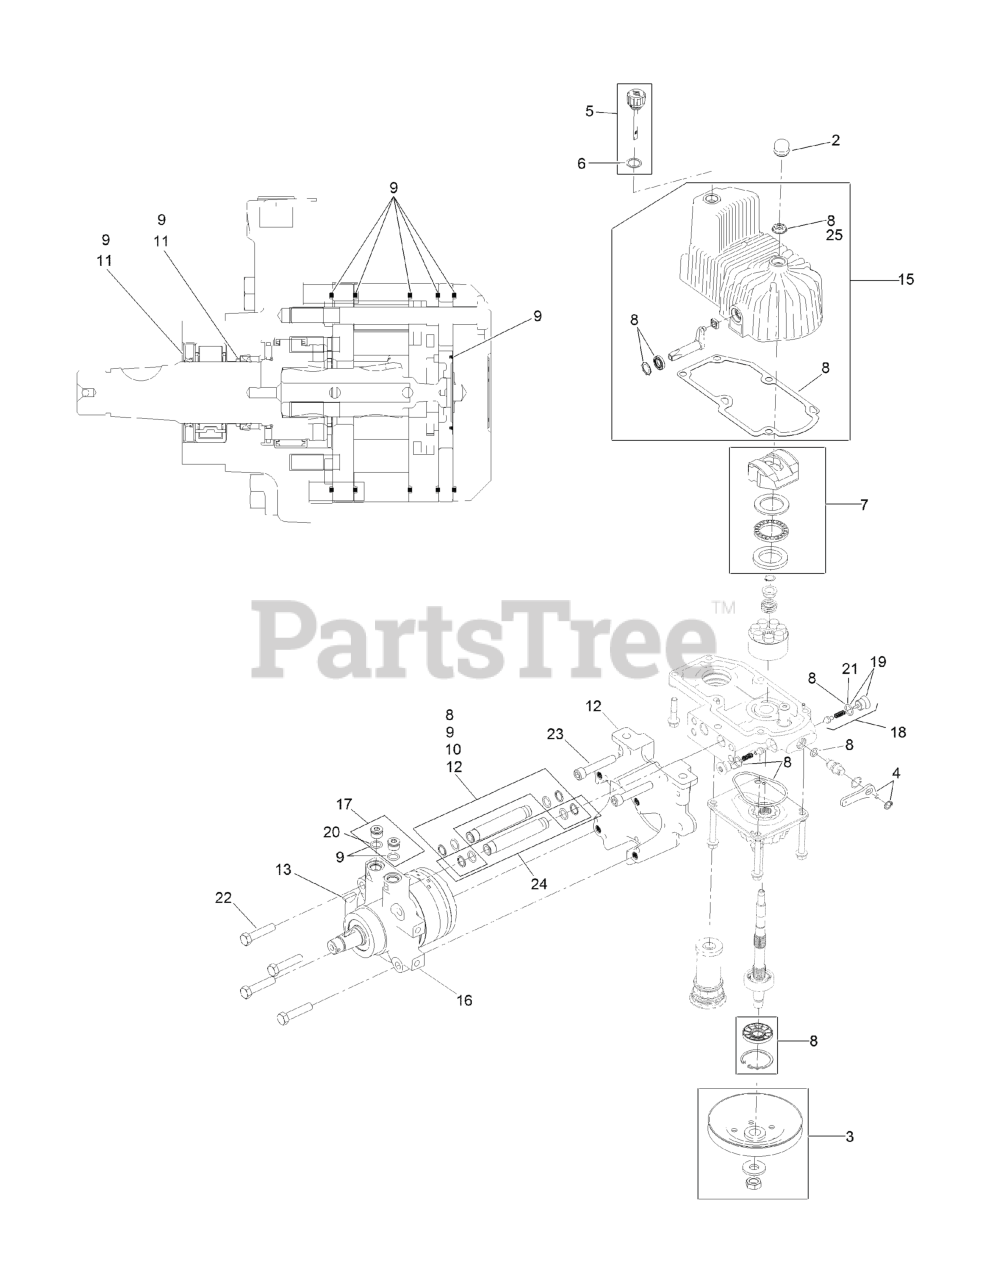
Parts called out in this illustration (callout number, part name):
2	COVER-SHAFT, HYDRO
3	PULLEY KIT
4	HANDLE-BYPASS VALVE, HYDRO
5	DIPSTICK-HYDRO W/GASKET
6	GASKET-DIPSTICK, HYDRO
7	SWASH BLOCK KIT
8	PUMP SEAL KIT
9	MOTOR SEAL KIT
10	TUBE SEAL KIT
11	OUTPUT SHAFT SEAL KIT
12	NOSE CUP-UHT
13	KEY-WOODRUFF
15	HOUSING-HYDRO, LH
16	MOTOR-HYDRAULIC LH 240CC
17	MAGNETIC PLUGS SERVICE KIT
18	CHECK VALVE ASM
19	PLUG-CHECK (W/O-RING)
21	O-RING-CHECK VALVE
22	SCREW HH
23	SCREW-HSH
24	HYDRAULIC TUBE KIT
25	SEAL-FAN DRIVE
26	KIT, PUMP SECTION 12CC LH NO FAN
27	ROTATING KIT
